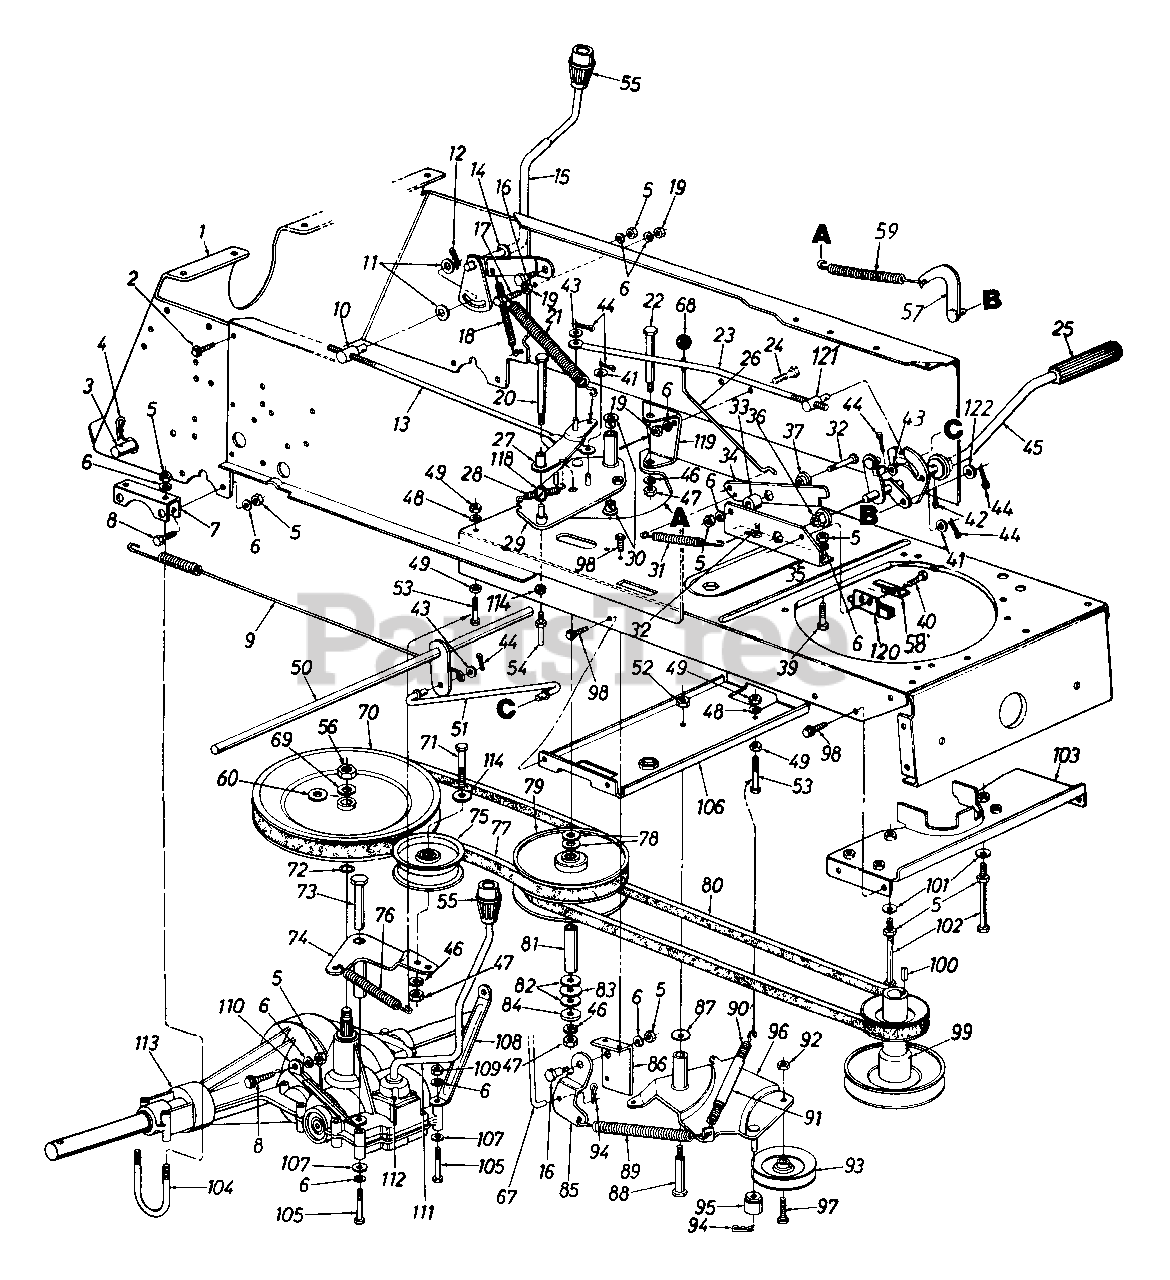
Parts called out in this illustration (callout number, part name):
3	Hitch Rod
4	Hitch Pin Clip
5	Hex Nut 5/16-18 Thd.
6	L-Wash. 5/16" I.D.
7	Transaxle Bracket
8	Hex Bolt 5/16-18 x .75" Lg. (Gr. 5)
9	Brake Extension Spring
10	Adjustment Ferrule 3/8-24 Thd.
11	Fl-Wash. .385" I.D. x .87"
13	Speed Control Link (Rear)
14	Fl-Wash. .531" I.D. x .94"
15	Speed Selector Lever Ass'y.
16	Shld. Bolt .437" Dia. x .162"
17	Hex Bolt 5/16-24 x 1.25" Lg.
18	Extension Spring 3.9" Lg.
19	Hex Nut 5/16-24 Thd. (Gr. 5)
20	Hex Bolt 3/8-24 x 4.5" Lg.
21	Extension Spring 11" Lg.
22	Shld. Bolt .625" Dia. x 3.5" Lg.
23	Speed Control Link (Front)
24	Hex Bolt 5/16-24 x .75" Lg.
25	Foot Pad
26	Parking Brake Link
29	Pulley Plate Ass'y.
30	Flanged Brg. .630" I.D.
31	Extension Spring 2.51" Lg.
32	Hex Bolt 5/16-18 x 1.25" Lg.
33	Spacer .34" I.D. x .88"
36	Hex Flange Brg. .634" I.D.
37	Shld. Spacer .5" Dia.
39	Hex Bolt 5/16-18 x .75" Lg.
40	Hex B-Tap Scr. #10 x 5/8 Lg.
41	Fl-Wash. .406" I.D. x .75" O.D.
42	Cotter Pin 1/8" Dia.
43	Fl-Wash. .34" I.D. x .68" O.D.
44	Cotter Pin 3/32" Dia.
47	Hex Nut 3/8-24 Thd.
48	L-Wash. 1/4" I.D.
49	Hex Nut 1/4-20 Thd.
50	Brake Link Bracket
51	Front Brake Rod Link
52	Hex Cent. L-Nut 3/8-16 Thd.
53	Hex Bolt 1/4-20 x 2.0" Lg.
54	Belt Guard Pin
55	Shift Knob
56	Hex Jam Nut 9/16-18 Thd.
57	Foot Pedal Brkt. Ass'y.
58	Switch Plate
59	Ext. Spring 5.2" Lg.
60	Fl-Wash. .635" I.D. x 1.12" O.D.
67	Deck Control Rod
68	Ball Knob Brake
69	Bell-Wash. 9/16" I.D. x 1.25"
70	V-Pulley 9 1/4" O.D.
71	Hex Bolt 3/8-24 x 1.75" Lg.
72	Wire Ring
73	Shld. Bolt 5/16-24 Thd.
74	Idler Brkt. Ass'y.
75	Flat Idler 3.5" O.D.
76	Extension Spring 6.12" Lg.
77	V-Belt
78	Teflon Washer 1.20" O.D.
79	Variable Speed Pulley 6" Dia.
80	V-Belt
81	Pivot Bushing
82	Fl-Wash. .56" I.D. x 1.0" O.D.
83	Thrust Brg. .56" I.D. x 1.25"
84	Retainer Cup
85	Deck Control Pivot Brkt.
86	Parking Brake Mtg. Brkt.
87	Bell-Wash. .38" I.D. x .88" O.D.
88	Shld. Bolt .498" Dia. x 2.05"
89	Extension Spring 6.12" Lg.
90	Extension Spring 6.37" Lg.
91	Convoluted Conduit 4" Lg.
92	Hex Cent. L-Nut 3/8-24 Thd.
93	V-Belt Idler
94	Internal Cotter Pin
95	Spacer
96	Idler Brkt. Deck Ass'y.
97	Hex Bolt 3/8-24 x 1.5" Lg.
98	Hex TT-Tap Scr. 1/4-20 x .5"
99	Engine Pulley
100	Sq. Key 1/4 x 1.5" Lg.
101	Bell-Wash. .345" I.D. x .88"
102	Hex Bolt 5/16-18 x 5.25" Lg.
103	Belt Keeper Brkt. Ass'y.
104	U-Bolt
105	Hex Bolt 5/16-24 x 2.25" Lg.
106	Deck Idler Support Brkt.
107	Fl-Wash. .344" I.D. x .62" O.D.
108	Front Trans. Support Brkt. - L.H.
109	Hex Nut 5/16-24 Thd.
110	Front Trans. Support Brkt. - R.H.
111	Shift Lever Ass'y. Complete
112	Socket Hd. Cap Scr. #10 x 24
113	2-Speed Transmission Comp.
114	Fl-Wash. 3/8" I.D. x 1.0" O.D.
118	Nyliner Flanged Brg.
119	Variable Speed Support Brkt.
120	Safety Switch (Clutch)
121	Adjustment Ferrule 3/8-24 Thd.
122	Fl-Wash. .344" I.D. x .62" O.D.
